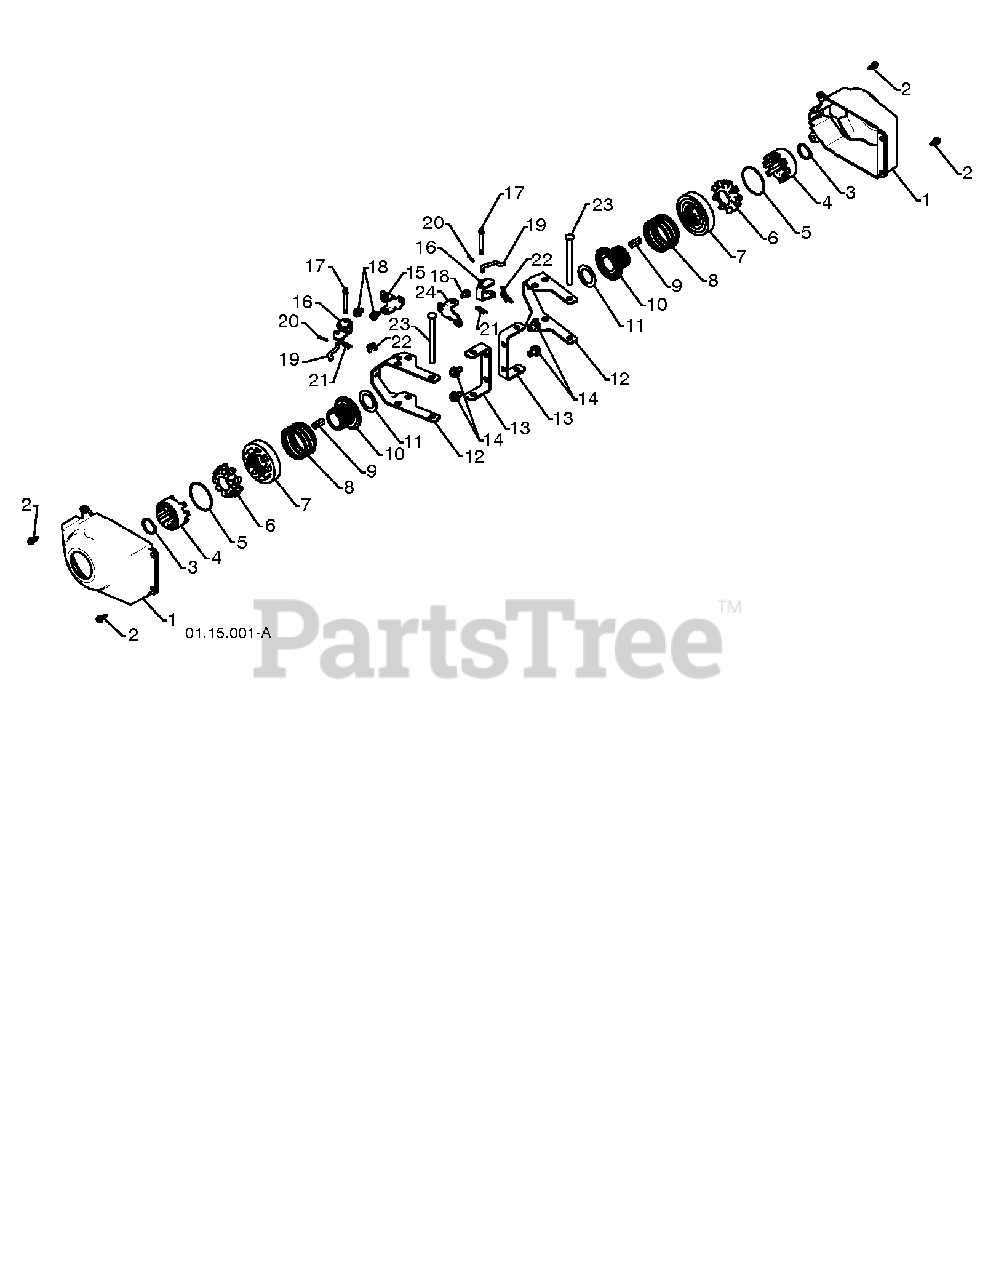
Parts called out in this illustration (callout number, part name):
1	COVER, POWER STEERING
2	SCREW, HEX HEAD, TAPPING
4	DRIVER WHEEL
5	RING, WIRE RETAINER
6	LOBE WHEEL
7	SLIDE.CLUTCH
8	SPRING, CLUTCH SLIDE
9	KEY, SQUARE 1/4 X .875
10	LOBE.AXLE
11	WASHER TRUST 1"
12	YOKE, STEERING
13	BRACKET.STEER.PNT.BLACK
15	BRKT.STEER.PIVOT.RH
16	BELLCRANK.STEER
17	PIN, STEERING BELLCRANK
19	LINK.STEER.YOKE
20	RETAINER CLIP
21	RETAINER CLIP PM
22	SPRING LATCH
23	PIN, STEERING LEVER
24	CONTROL SHAFT
